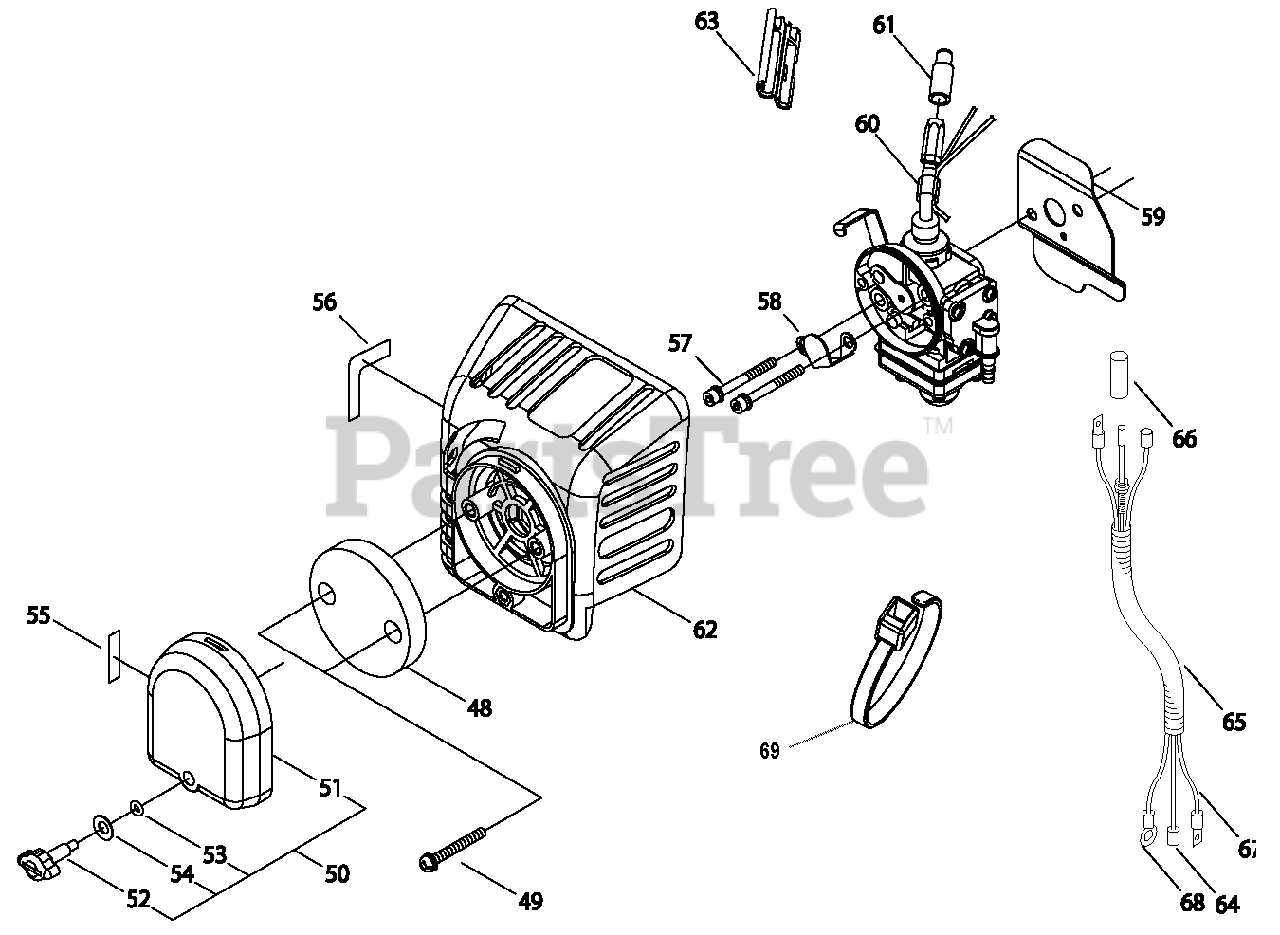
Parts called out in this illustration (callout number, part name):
48	FILTER, AIR
49	SCREW M4×25
50	COVER ASSY, AIR FILTER
51	COVER, AIR FILTER
52	THUMBSCREW
53	O-RING
54	WASHER, CONE M6
55	LABEL, CHOKE
56	LABEL, CARBURETOR
57	BOLT
58	PLATE
59	GASKET, CARBURETOR
60	TUBE, PROTECTIVE
61	CAP, CARBURETOR
62	CASE, AIR FILTER
63	CAP, DUST
64	CABLE, THROTTLE
65	TUBE, FLEXIBLE
66	SLEEVE
67	LEAD - IGNITION
68	LEAD - GROUND
69	TIE, CABLE
